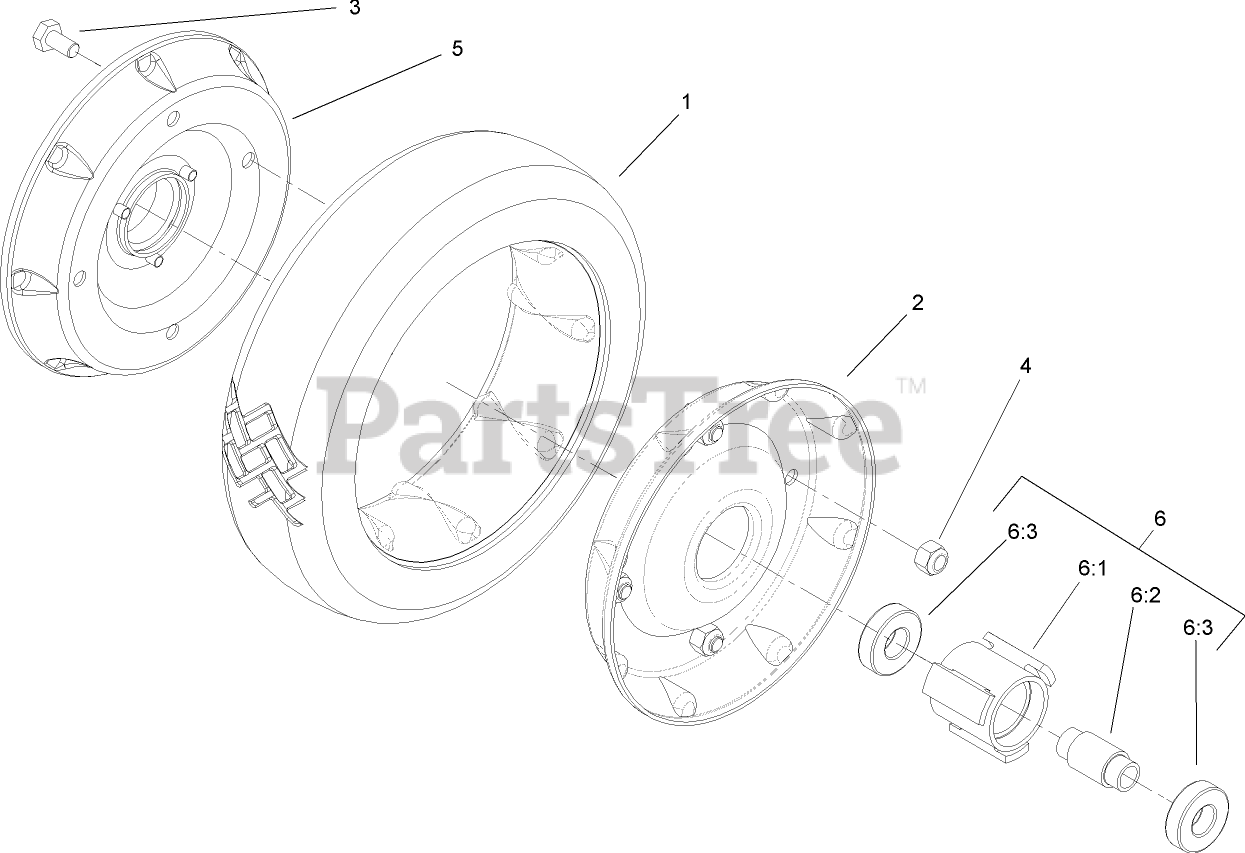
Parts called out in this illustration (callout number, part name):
3	SCREW-HH
4	NUT-LOCK, NI
6	Loose Parts Package
6:1	HUB-BEARING
6:2	SPACER-BEARING
6:3	BEARING-WHEEL
